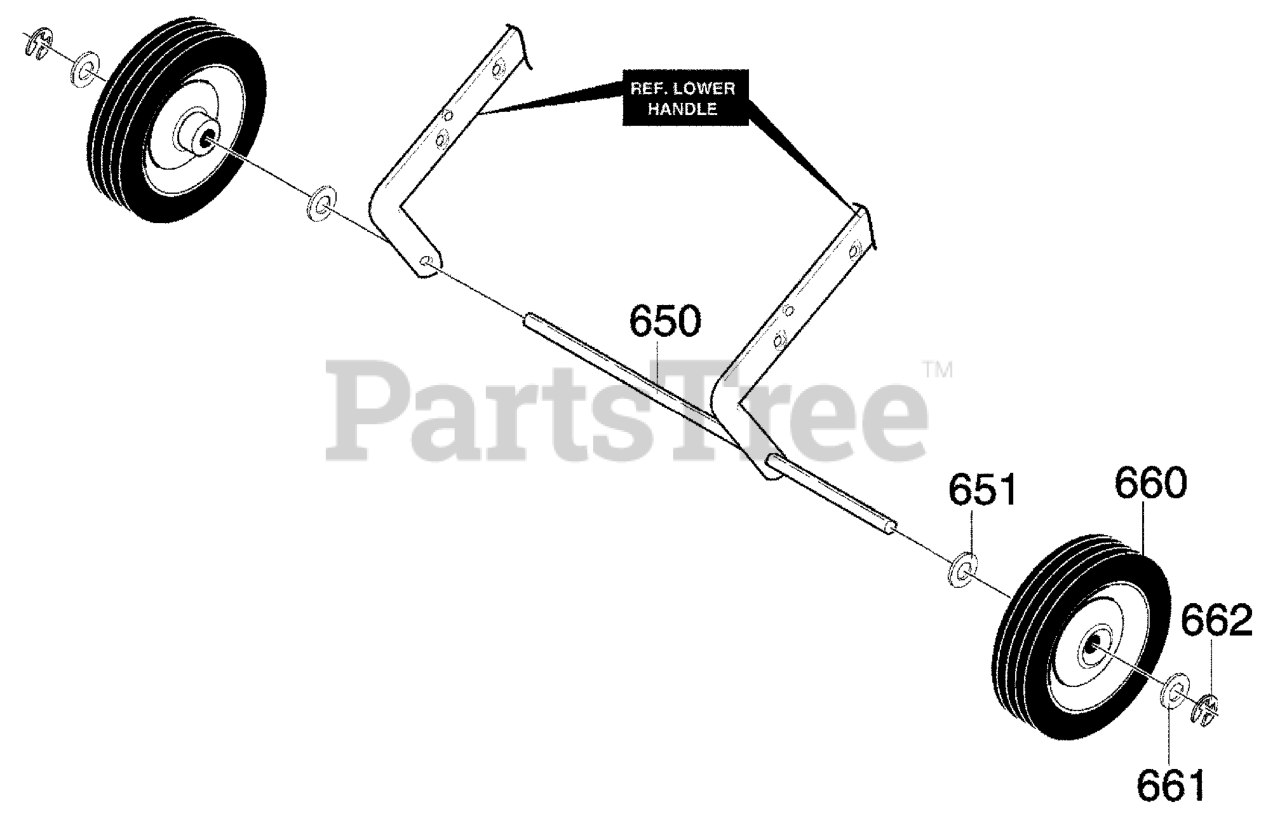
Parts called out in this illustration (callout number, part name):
650	AXLE SHAFT
651	WASHER, FLAT .391X1.00X1.25
660	TIRE & RIM
661	WASHER, FLAT .391X1.00X.125
662	RING, RET E
